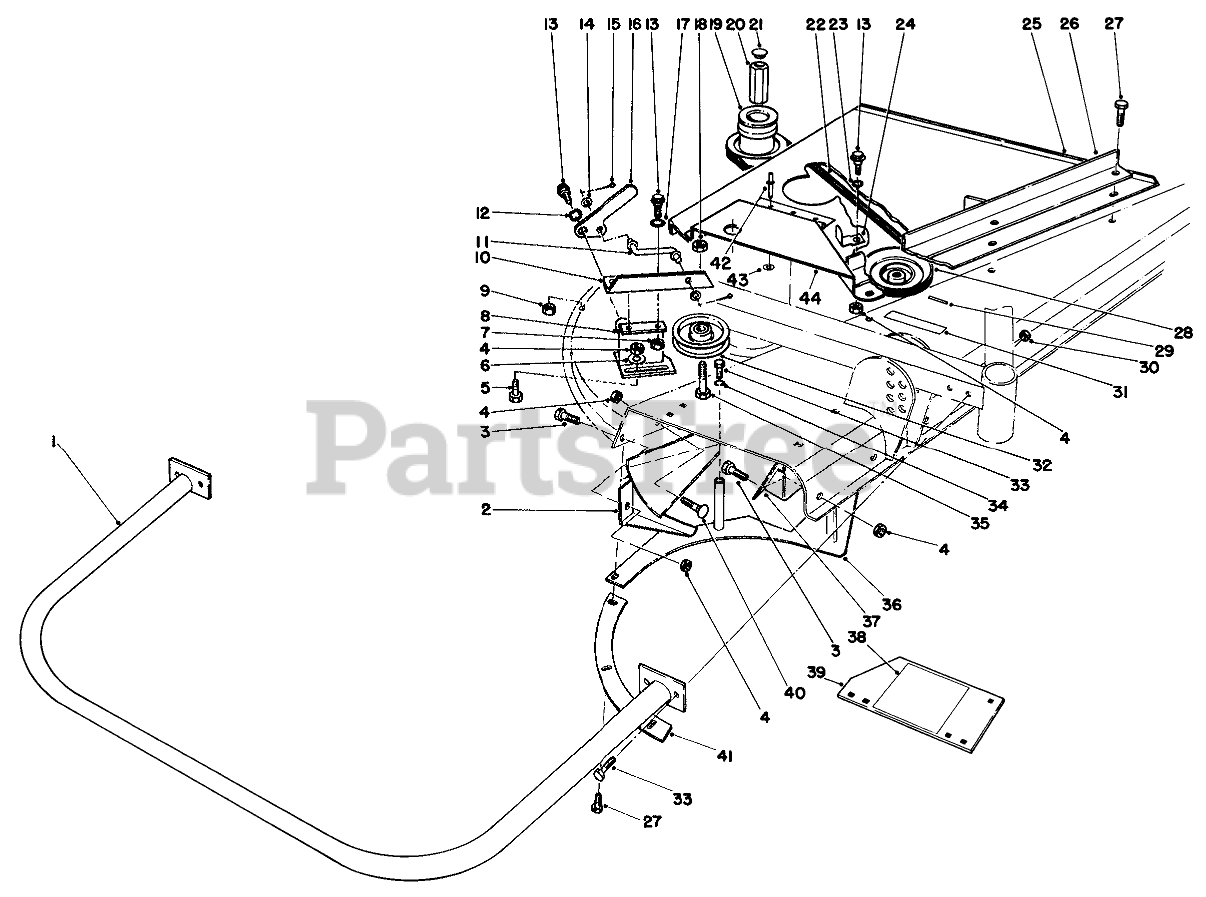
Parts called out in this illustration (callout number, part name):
1	Bumper
2	Deflector-Rear
3	SCREW-HH
4	NUT-LOCK, CONE
5	SCREW-HH
6	WASHER-FLAT
7	NUT-LOCK, NI
8	Bracket-Idler
9	NUT-LOCK, CONE
10	Slide-Idler
11	Idler Rod
12	WASHER-SPRING
13	SCREW-SHOULDER
14	WASHER-PLAIN
15	PIN-COTTER
16	Lever-Idler
17	WASHER
18	NUT-LOCK, NI
19	Pulley (Splined)
20	NUT-PULLEY
21	NUT-COVER
22	V-BELT
23	WASHER-SPRING
24	Latch
25	RH COVER WA R
26	Spring Bracket
27	SCREW-HH
28	Pulley-Gear Box
29	PIN-ROLL, SLOTTED
30	NUT-LOCK, CONE
31	WARNING DECAL
32	PULLEY-IDLER
33	SCREW-HH
34	WASHER-LOCK
35	SCREW-HH
36	Rear Shelf
37	Front Deflector
38	Decal-Caution
39	Cover Plate Assembly (Incl. Ref. #38)
40	BOLT-CARR
41	Shelf-RH
43	WASHER-FLAT
44	PULLEY COVER WA R
